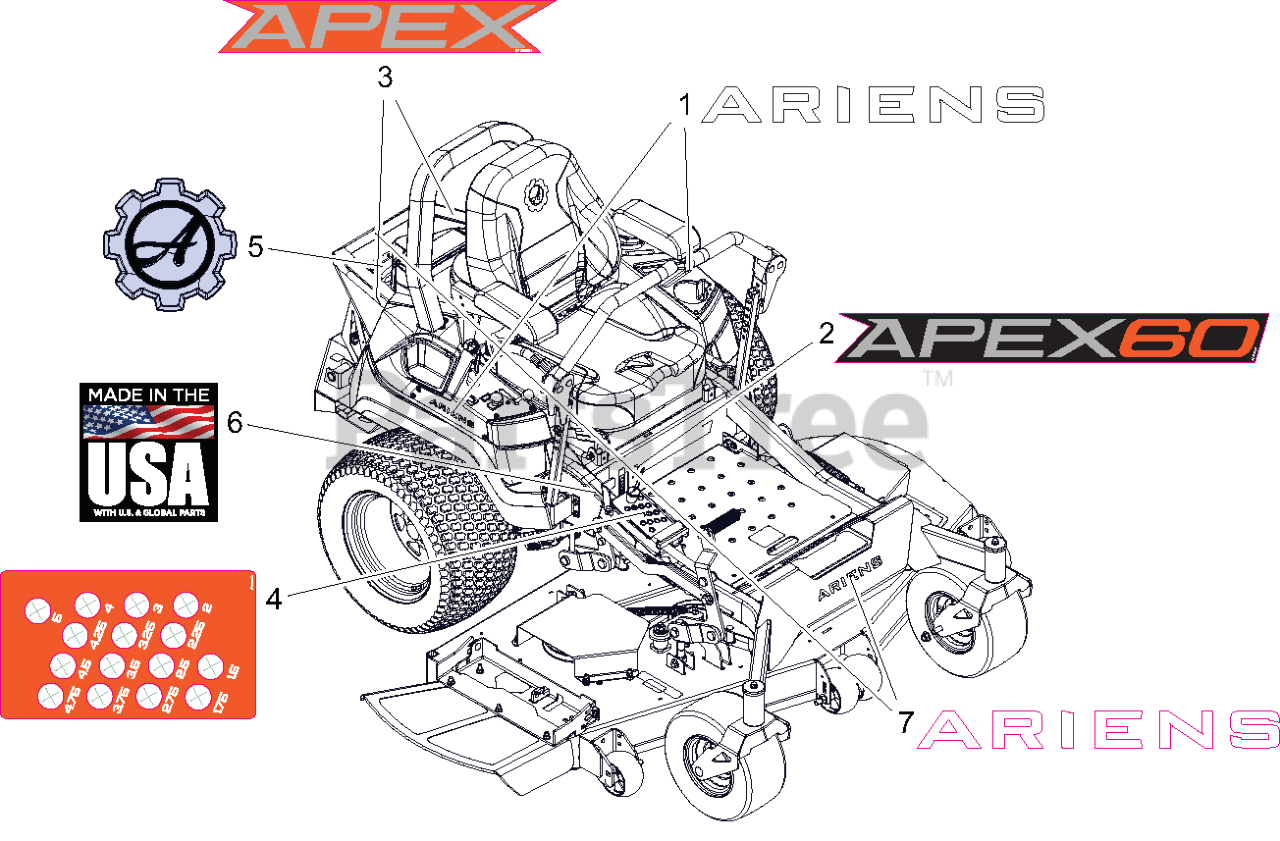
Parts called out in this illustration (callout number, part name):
1	DECAL, ARIENS (6.50")
2	DECAL, 60" APEX KICKPLATE
3	DECAL, APEX FENDER
4	DECAL, ARIENS HOC
5	DECAL, ARIENS - GEAR BADGE
6	DECAL, MADE IN USA
7	DECAL - ARIENS 9.625"
